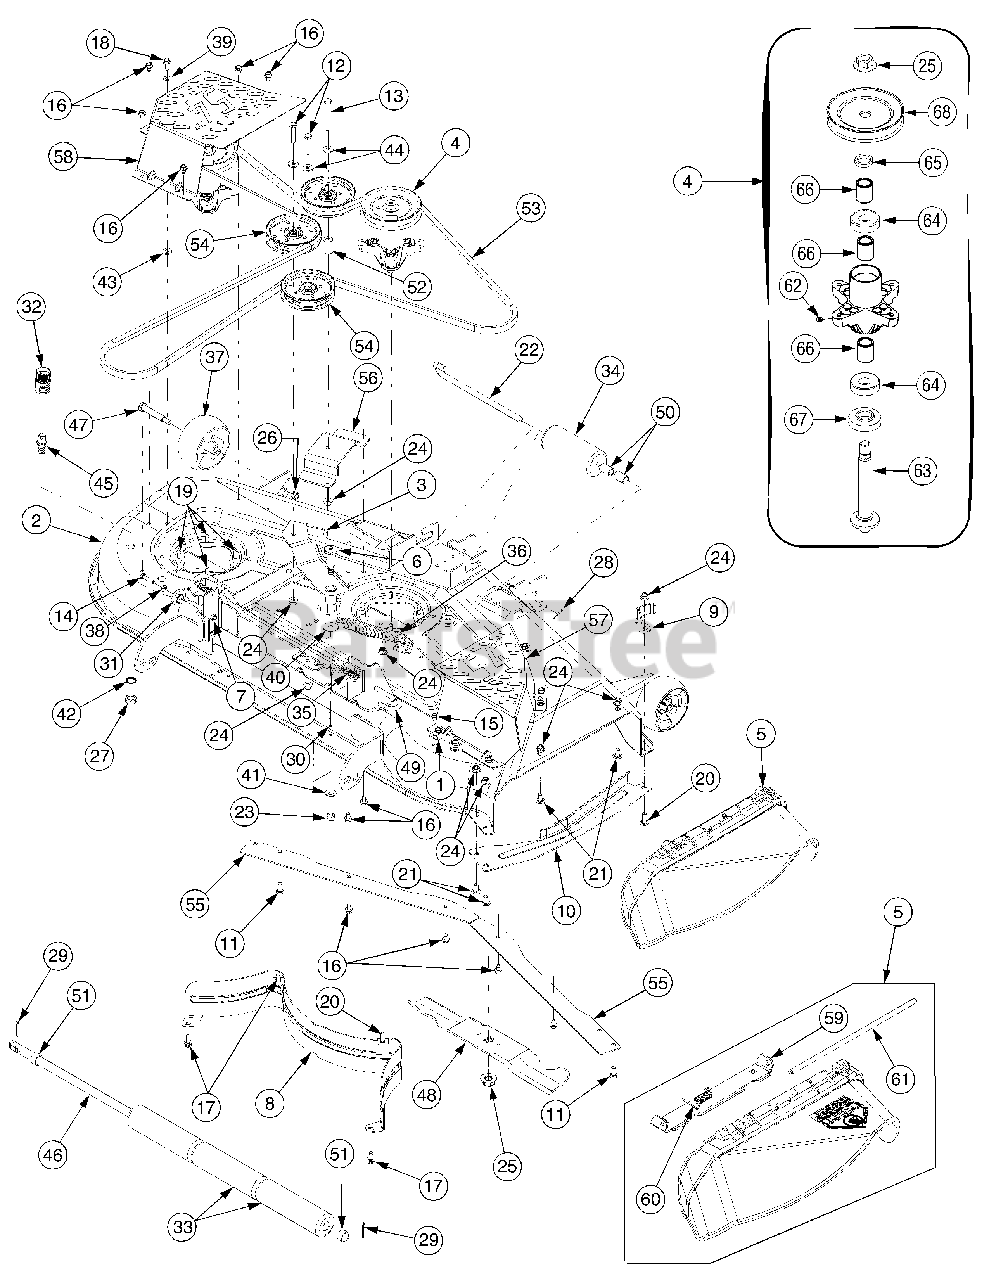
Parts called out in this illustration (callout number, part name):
1	Bracket, Retainer
4	Spindle Assembly
5	Chute Assembly, Discharge
6	Bolt Assembly, Shoulder
11	Screw, Hex Cap, 3/8-16 x .75 Gr5 ..
12	Screw, Hex Cap, 3/8-16 x 1.75 Gr5
13	Screw, Hex Cap, 3/8-16 x 3.0 Gr8 ..
14	Screw, Hex Cap, 5/16-18 x 1.25 Gr5
15	Screw, Hex Wash. Hd. Tapp 1/4-20 x .5
16	Screw, Hex Wash. Hd. Tapp 5/16-18 x .5
17	Screw, Hex Wash. Hd. Tapp 3/8-16 x .75
18	Screw, Hex Wash. Hd. Tapp 5/16-18 x .875
19	Screw, Hex Wash. Hd. Tapp 5/16-18 x .75
20	Screw, Carriage, 3/8-16 x 1.0
21	Screw, Carriage, 3/8-16 x .75
22	Pin, Roller, .5 x 10.06
23	Nut, Hex Lock, 7/16-14
24	Nut, Hx Insert Flange Lck, 3/6-16 GrF
25	Nut, Hex Flange, 5/8-18
26	Nut, Hex Flange Lock, 3/8-16 GRF
27	Nut, Hex, M16-1.5
28	Pin, Cotter, 3/32 x 1.0
29	Pin, Cotter, 5/32 x 1.25
30	Pin, Cotter, 1/8 x 1.25
31	Gear, Deck Adjustment
32	Adapter, Water Nozzle
33	Roller, Deck, 7.895
34	Roller, Front
35	Spring, Compression
36	Spring, Extension, .94 Dia. x 6.74 ..
37	Wheel, Deck Ball, 5.0
38	Washer, Lock, 5/16
39	Washer, Flat, .344 x .688 x .065
40	Washer, Flat, .442 x 1.39 x .06
41	Washer, Bell, .45 x 1.0 x .062
42	Washer, Lock,
43	Washer, Flat, .407 x .812 x .135 HT
44	Washer, Flat, .38 x .93 x .110 HT ...
45	Nozzle, Deck Wash
46	Shaft, .75 x 26.893
47	Screw, Shoulder, .5 x 2.5:3/8-16
48	Blade, 18.5 Lg
49	Rod, Deck Hanger
50	Spacer, .55 x .75 x 1.125
51	Spacer, .82 x 1.0 x.53
52	Spacer, .38 x .9 x 1.313
53	Belt V, Type B Sec x 143
54	Pulley, Idler, 4.25 Dia
59	Bracket, Chute Mounting
60	Spring, Torsion
61	Pin, Hinge
62	Fitting, Lube
63	Shaft, Spindle, 6.95
64	Bearing, Ball
65	Spacer, .79 x 1.25 x .175
66	Spacer, .80 x 1.10 x 1.32
67	Spacer, .79 x 1.82 x .55
68	Pulley, V Type, 5.39
